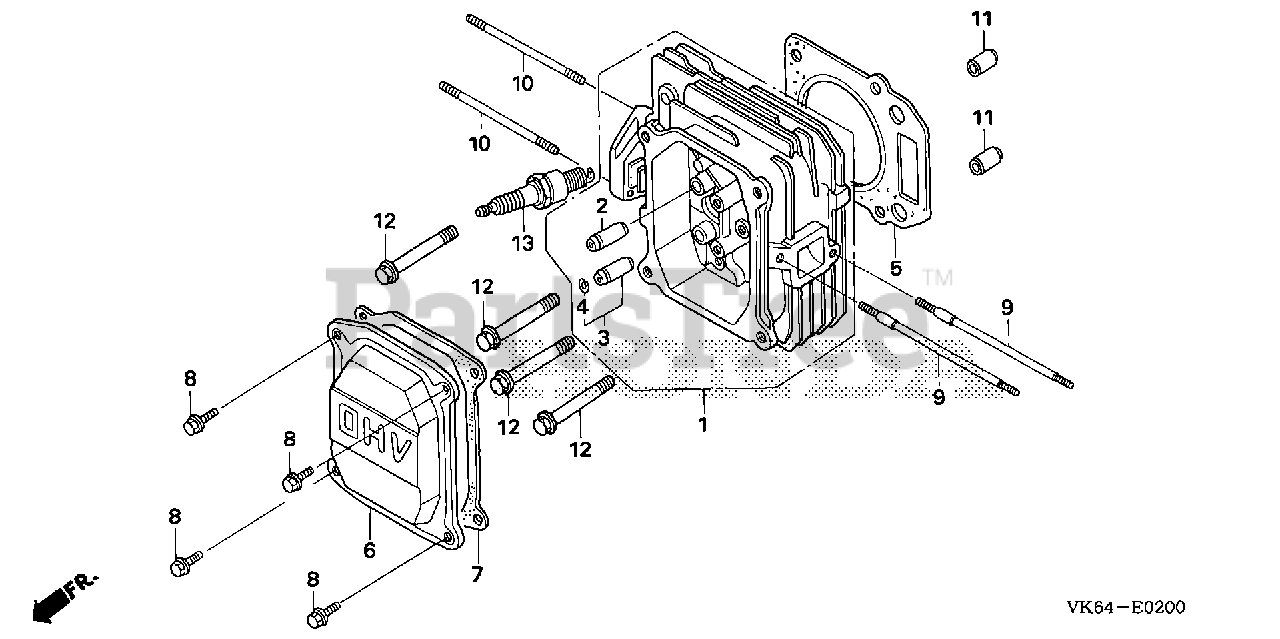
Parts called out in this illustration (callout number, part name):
1	CYLINDER HEAD
2	GUIDE, VALVE (OVER SIZE) Use from Engine SN 6324986.
3	GUIDE, EX. VALVE (OS)
4	CLIP, VALVE GUIDE Use from Engine SN 1231803.
5	GASKET, CYLINDER HEAD (GUANGZHOU LEAKLESS)
5	GASKET, CYLINDER HEAD (NINGBO SIL GASKET)
6	COVER, HEAD
7	GASKET, HEAD COVER (NINGBO SIL GASKET)
7	GASKET, CYLINDER HEAD COVER
8	BOLT, FLANGE (6X14)
9	BOLT, STUD (6X97)
10	BOLT, STUD (6X85)
11	PIN A, DOWEL (10X16)
12	BOLT, FLANGE (8X50)
13	SPARK PLUG (BPR4ES) (NGK)
13	SPARK PLUG (W14EPR-U) (DENSO)
13	SPARK PLUG (BPR5ES) (NGK)
13	SPARK PLUG (W16EPR-U) (DENSO)
13	SPARK PLUG (BPR6ES) (NGK)
13	SPARK PLUG (W20EPR-U) (DENSO)
